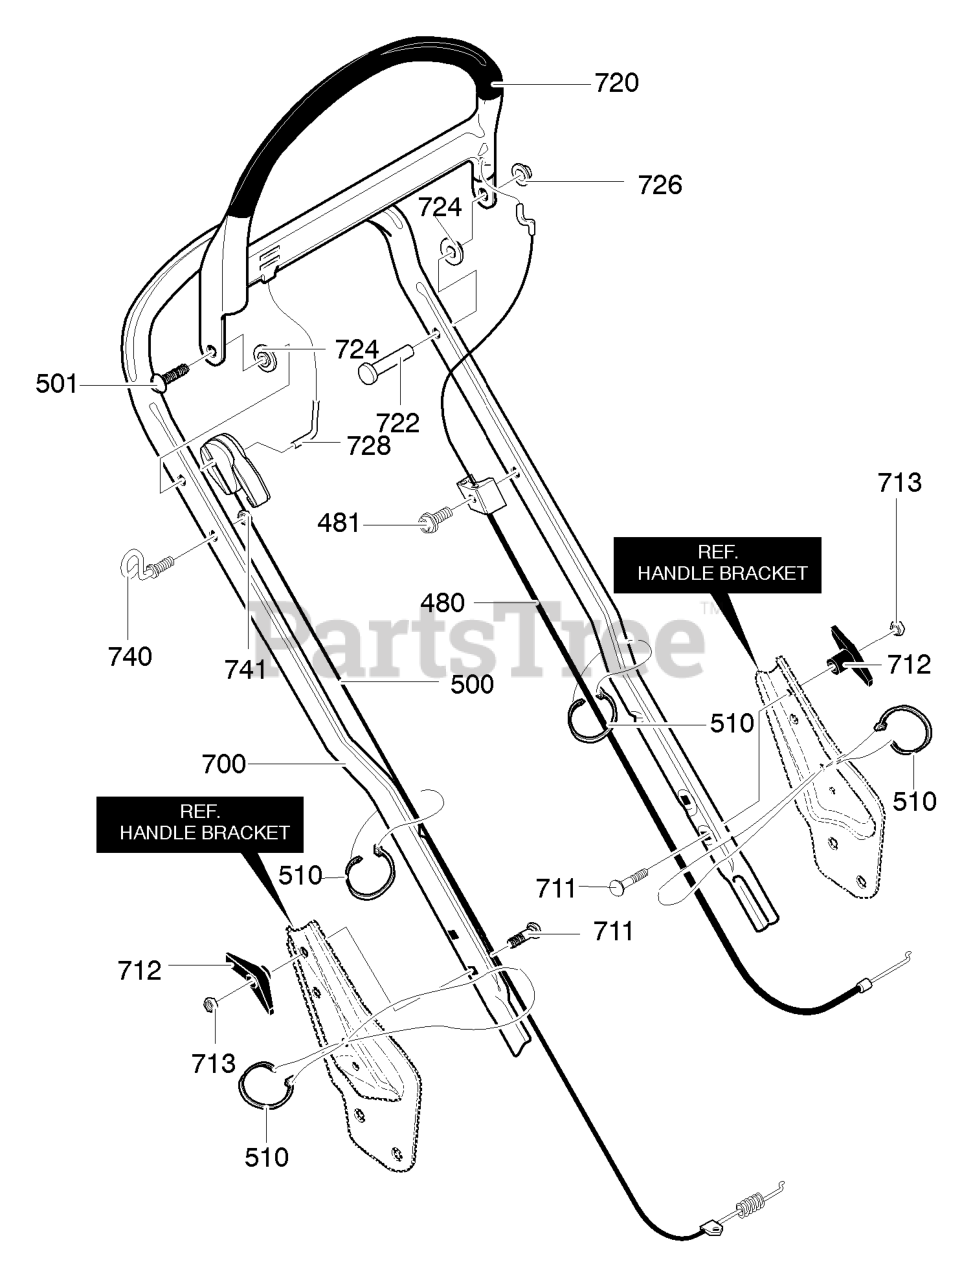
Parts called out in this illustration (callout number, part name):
480	CABLE,STOP
481	SCREW, 10-16X.75 S
500	CABLE, DRIVE
501	SCREW,#10-16X1.38
510	TIE, CABLE BLACK NYLON 5.62L
711	BOLT, 5/16-18X2.00
712	KNOB, T W/516/18 NUT
713	NUT, 5/16-18 REGHEX
720	LEVER, STOP FLAT
722	PIN, CLEVIS
726	RETAINER CAP
728	ROD, LINK
740	GUIDE, ROPE 1/4-20
741	NUT, 1/4-20
